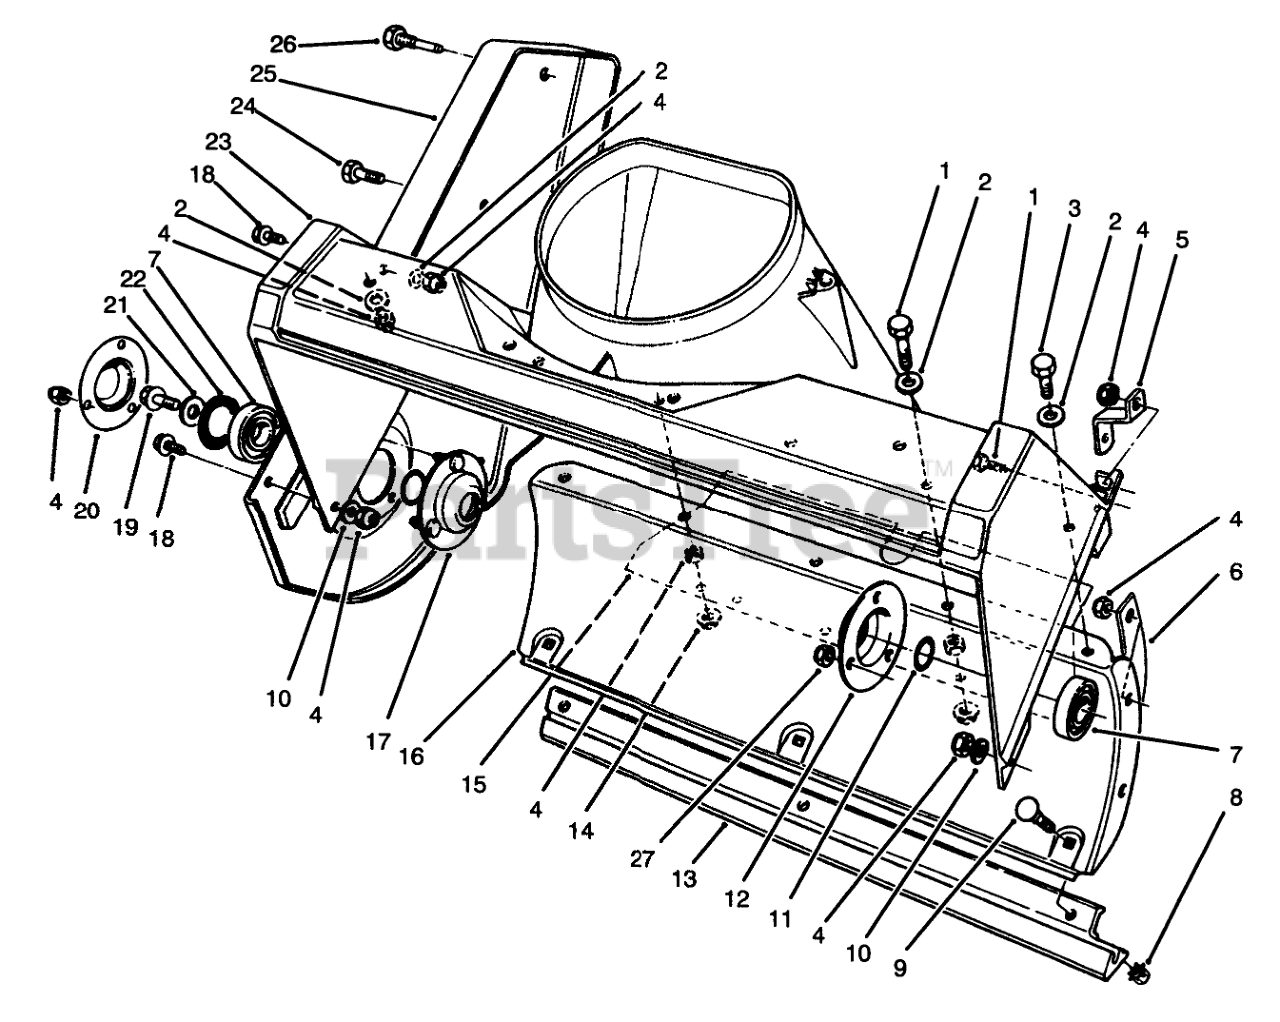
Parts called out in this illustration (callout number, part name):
1	SCREW-HH
2	WASHER-FLAT
3	SCREW-HH
4	NUT-LOCK, NI
5	BRACKET-HOUSING
6	BRACKET-HOUSING, LOWER
7	BEARING-BALL
8	NUT-KEPS
9	SCREW-CARR
10	WASHER-FLAT
11	WASHER-THRUST
12	FLANGE-BEARING
13	SCRAPER
14	NUT-LOCK, HHF
15	COVER-BOTTOM
16	Housing-Lower
17	FLANGE-BEARING
18	SCREW-HWH
19	SCREW-HHF
20	Trough
21	WASHER-FLAT
22	WASHER-RUBBER
23	HOUSING
24	SCREW-HH
25	Sideplate-RH
26	PIN-ROTOR
27	NUT-LOCK, NI
